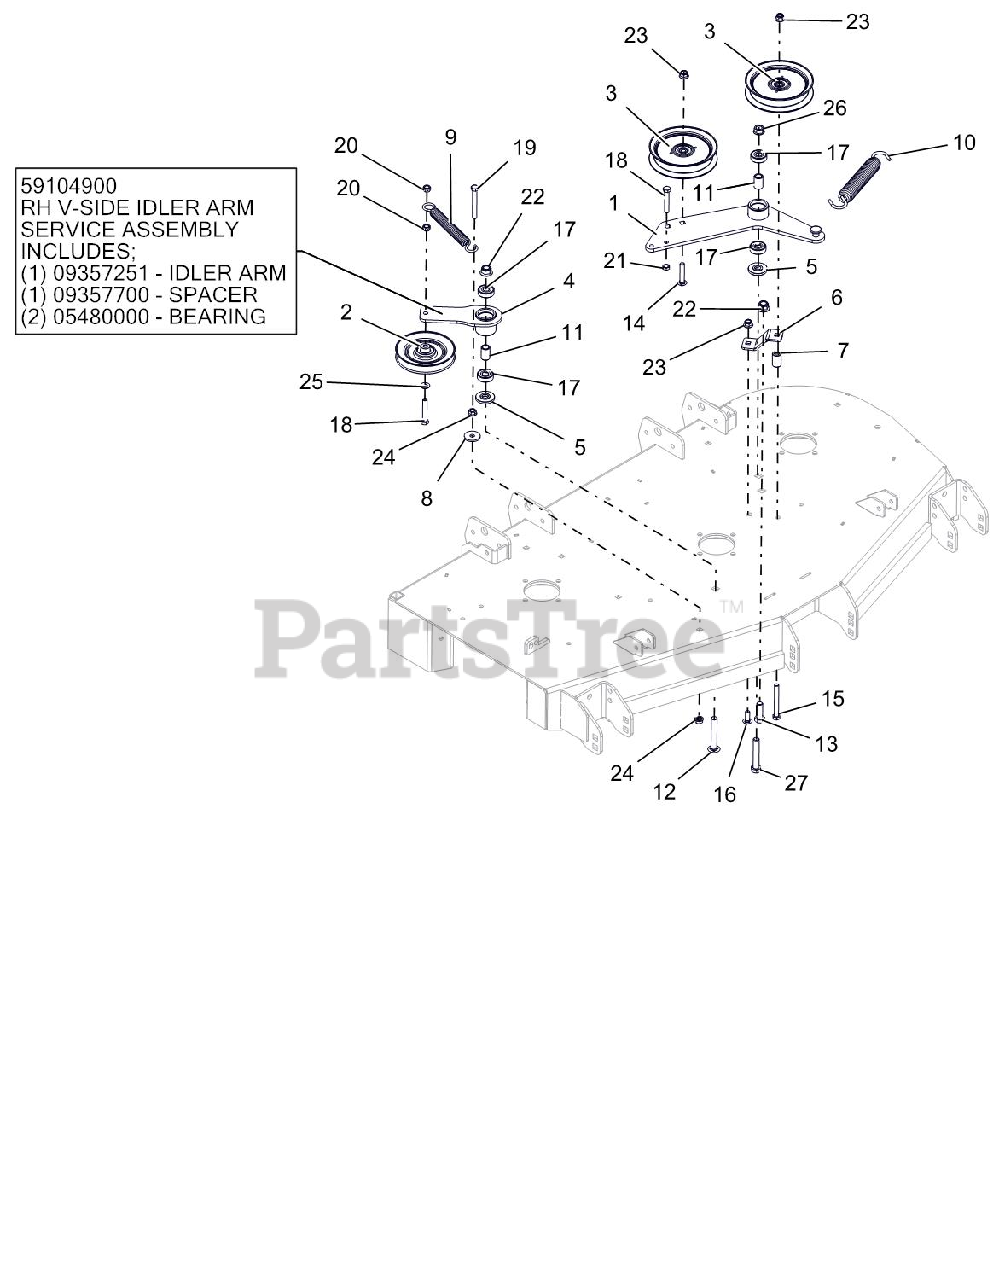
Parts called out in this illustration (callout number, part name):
1	WLDMT, DECK PTO IDLER ARM
2	IDLER, V-5.00" W/.69 STANDOFF
3	IDLER, FLAT
4	WLDMT, DECK RH IDLER ARM
4	RH V-SIDE IDLER ARM SERVICE ASSEMBLY
4	IDLER ARM
4	SPACER
4	BEARING
5	SPACER, IDLER ARM
6	BRKT, PTO FIXED IDLER MTG
7	BUSHING, SLV .380 X .750 X 1.190
8	WASHER-FLAT-STL, .406 X 1.375 X .135
9	SPRG, EXTENSION - SWIVEL
10	SPRG, EXTENSION
11	SPACER, .510 X .750 X 1.148
12	BLT-RDHDSQSHNK .50-13X3.25 YWZC
13	BOLT, HEX 0.5-13X1.5 GR5
14	BLT-RHDSSQNK .38-16X2.00 G5YZ
15	BOLT, HEX 0.375-16X3.25 GR5
16	BLT-RDHDSHSQNK.38-16X1.0 G5YZ
17	BRG-BALL .500X1.375X.44
18	BOLT, HEX 0.375-16X2.25 GR5
19	BOLT, HEX 0.375-16X3 GR5
20	NUT-LK-CTR .38-16 YWZC
21	NUT, JAM .375-16 YWZC
22	NUT-LK-NYL-FLG .50-13 YWZC
23	NUT-LK-NYL-FLG .38-16 YWZC
24	@NUT-SPNLK-FLG .375-16 YWZC
25	WSHR-FL-STL.406X.812X.065 YWZ
26	NUT-LK-CTR-FLG .50-13 YWZC
27	BOLT, HEX 0.5-13X3 GR5
